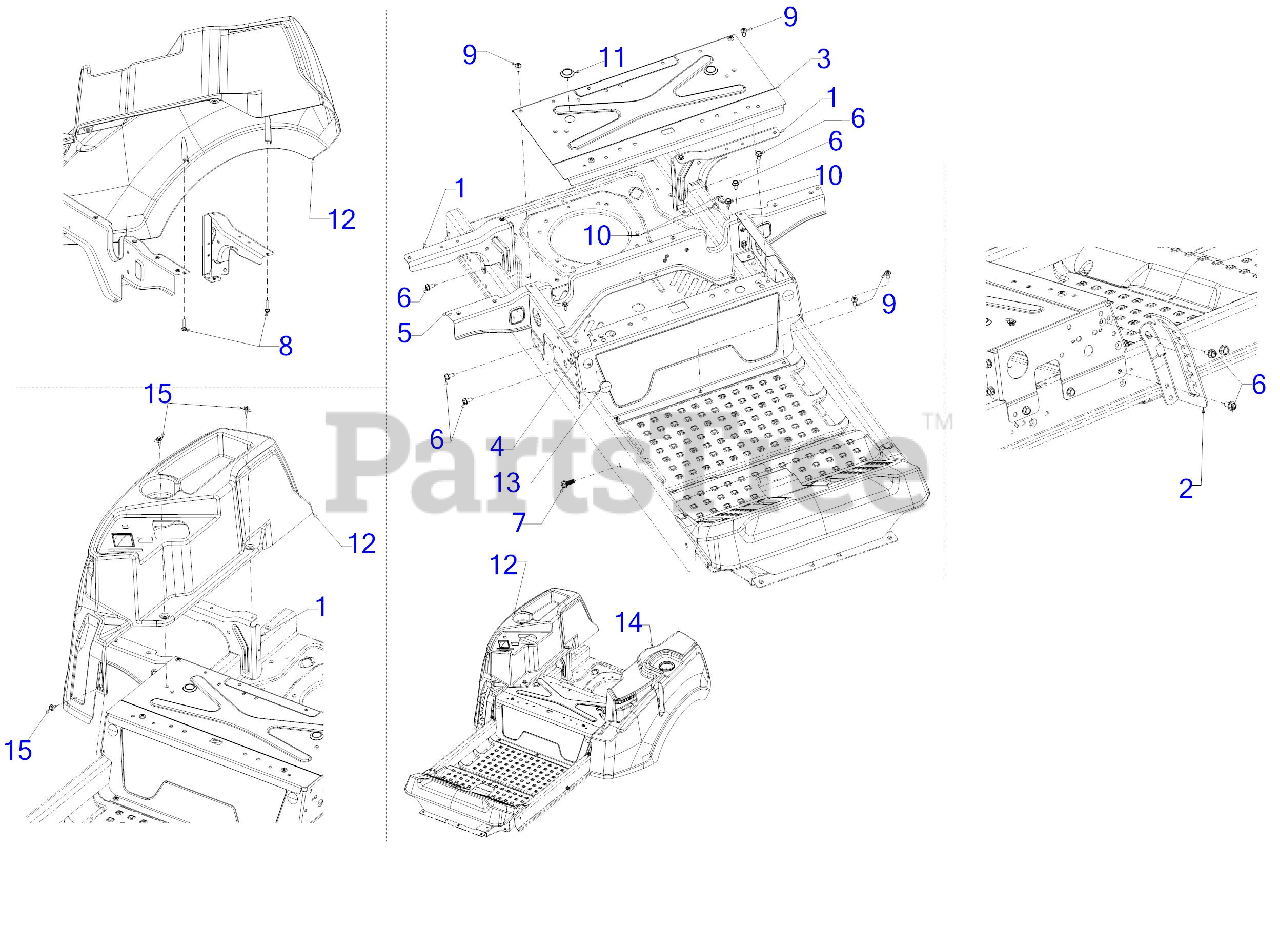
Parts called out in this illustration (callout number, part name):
2	HEIGHT INDEX BRACKET
6	SCREW 5/16-18 x .750
7	SCREW 3/8-16 x 1
8	SCREW 5/16-14 x 1
9	SCREW 5/16-18 x .750
10	SCREW 5/16-18 x .500
12	CONSOLE (RH)
13	PLASTIC PLUG
14	CONSOLE (LH)
15	SHOULDER SCREW M6-1 .368 X.115
